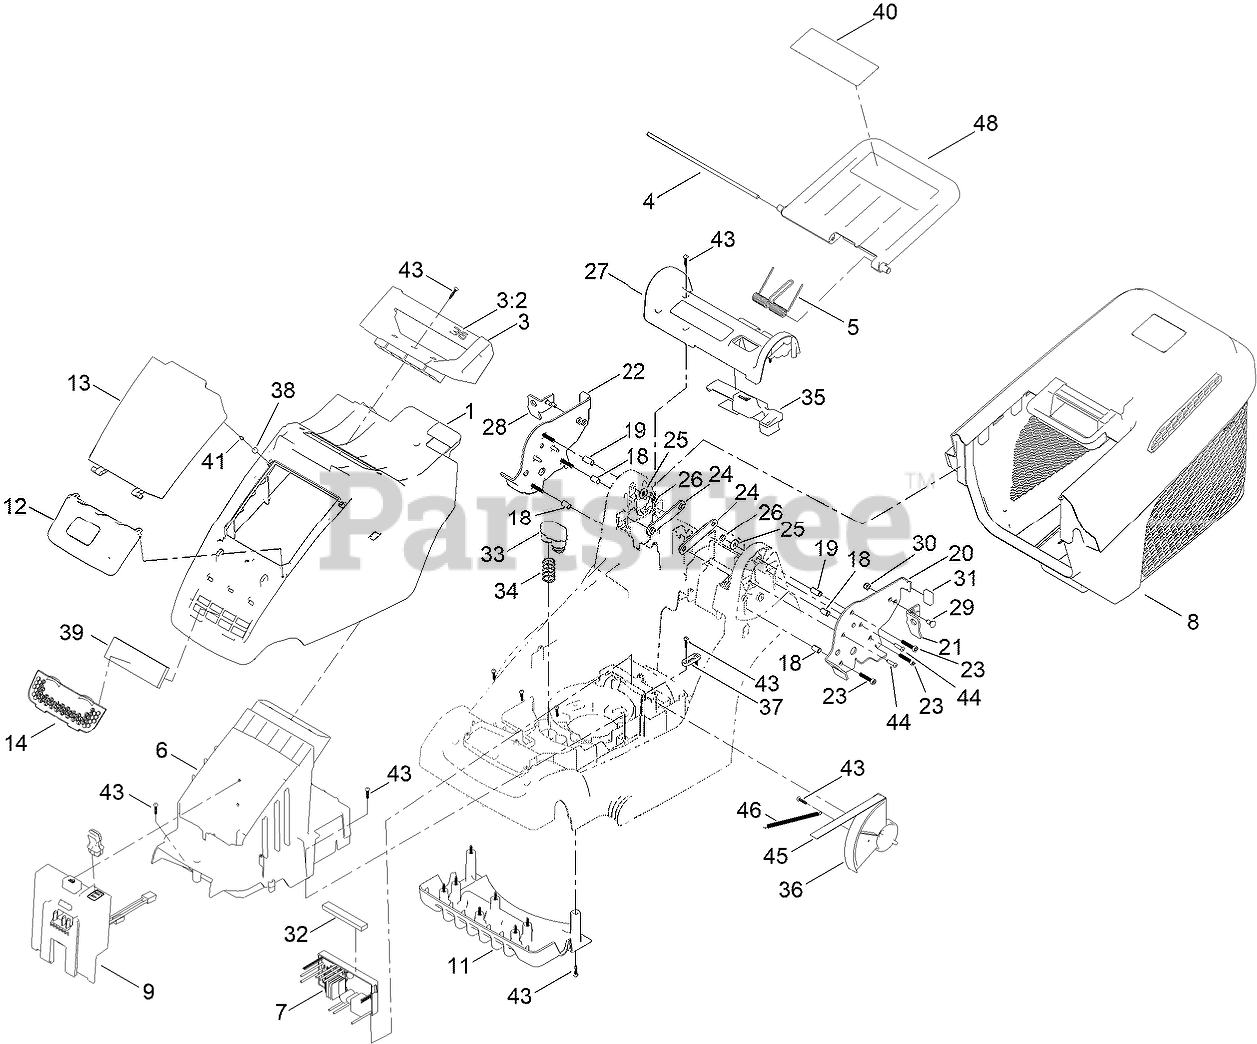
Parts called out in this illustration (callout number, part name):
1	TOP COVER
3	CARRY HANDLE
3:2	ARTWORK - 36CM
4	ROD, REAR FLAP
5	SPRING, REAR DEFLECTOR
6	Guard, Flywheel
7	DRIVER-MOTOR, 36CM
8	GRASS BOX ASM
9	BATTERY INTERFACE ASSEMBLY
11	FRONT FINS
12	BATTERY DOOR LOWER, PRINTED
13	BATTERY DOOR, PRINTED
14	AIR INLET GRILL-TORO
20	MOUNT PLATE, HANDLEBAR, LEFT
21	BRACKET, V-STOW, LEFT
22	MOUNT PLATE, HANDLEBAR, RIGHT
24	BRACE-BAR
25	WASHER
27	HOC COVER
28	BRACKET, V-STOW, RIGHT
29	BOLT, CARRIAGE, M6X1
30	NUT, NYLOC, M6X1
31	RUBBER FOOT-V-STOW
32	FILTER, AIR-CONTROL BOARD
33	BATTERY SPRING COVER
34	SPRING, BATTERY EJECT
35	HOC BUTTON, 36CM
36	HOC DIAL
38	MAGNET
39	Cover, Exhaust-Right
40	DECAL SAFETY 60V
41	PT SCREW 3MM X 10MM CSK
44	SCREW-TORX
45	DECAL - HOC
46	SPRING
48	REAR DEFLECTOR, TORO
